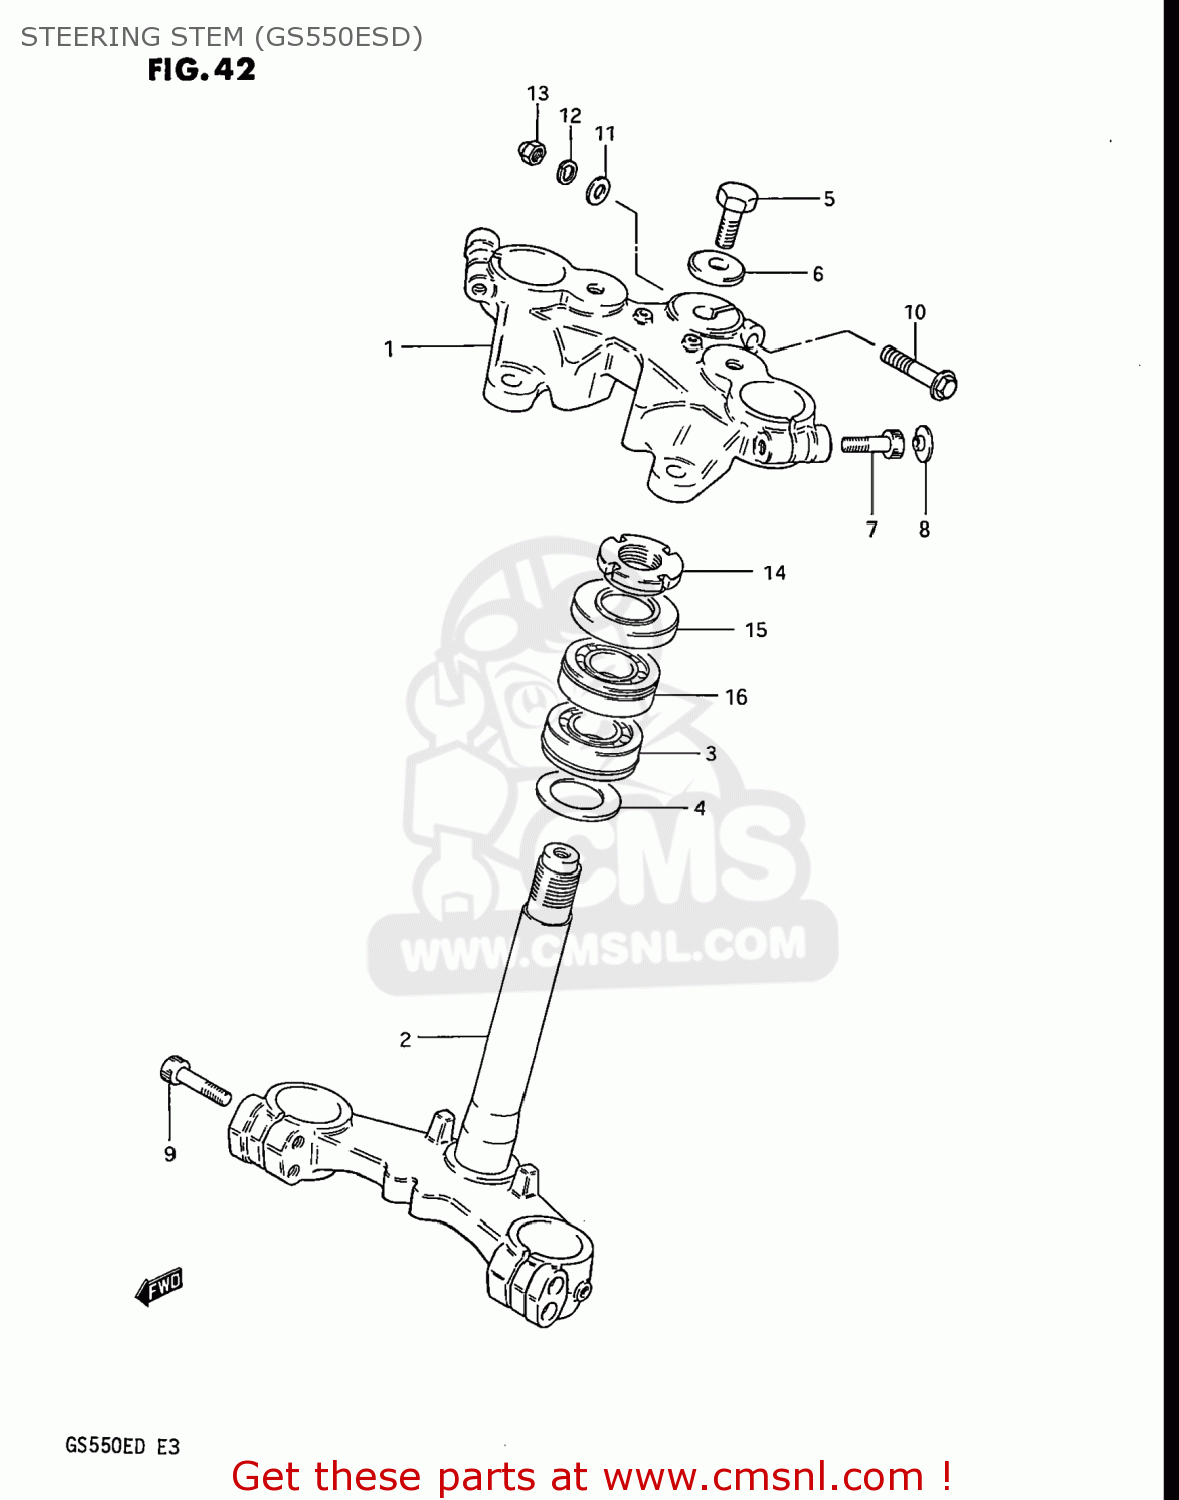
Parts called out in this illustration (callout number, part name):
1	HEAD,STEERING STEM
2	STEM,STEERING
3	BEARING
4	WASHER,THRUST
5	SUZUKI
6	SUZUKI
7	BOLT
8	CAP(OD:20)
9	BOLT
10	BOLT (8X50)
11	WASHER,8.5X16X
12	LOCK WASHER
13	NUT,M8X1.25X12
14	NUT,STEERING STEM
15	DUST SEAL,STEERING UPR
16	TAPER,ROLLER BEARING
